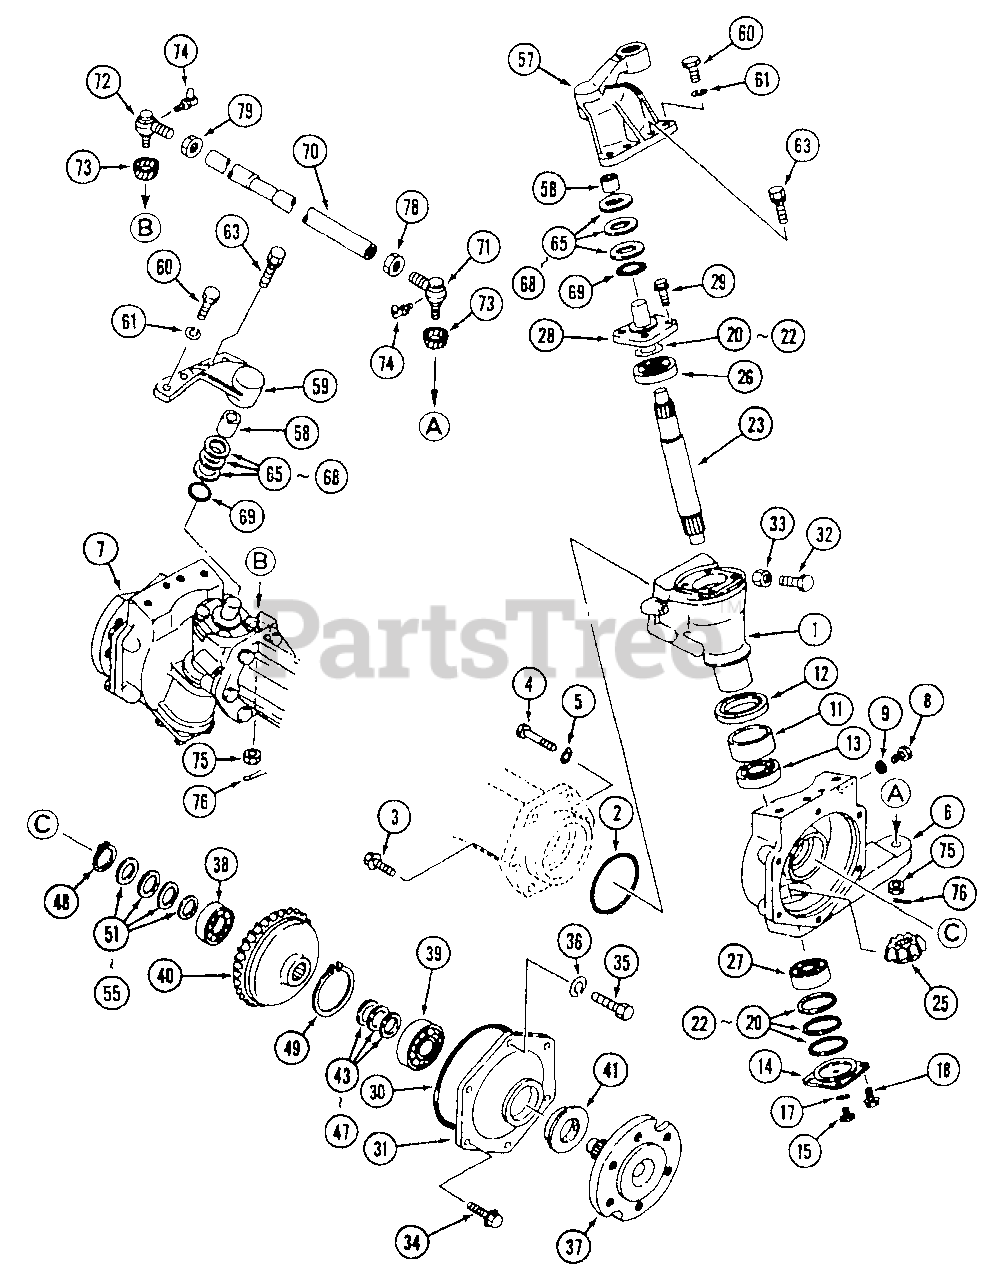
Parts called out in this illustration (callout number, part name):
1	Case, Kingpin
6	Case, Final L.H.
7	Case, Final R.H.
40	Gear, 32T
54	Liner t=1.0
57	Knuckle, Arm L.H.
59	Knuckle, Arm R.H.
65	Liner, Thrust
66	Liner, Thrust
67	Liner, Thrust
68	Liner, Thrust
71	End Ass'y-Tie Rod L.H. Side (R.H. Thread)
72	End Ass'y-Tie Rod R.H. Side (L.H. Thread)
73	Cover, Dust
74	Nipple, Grease
78	Nut (R.H. Thread) M17
79	Nut (L.H. Thread) M17
